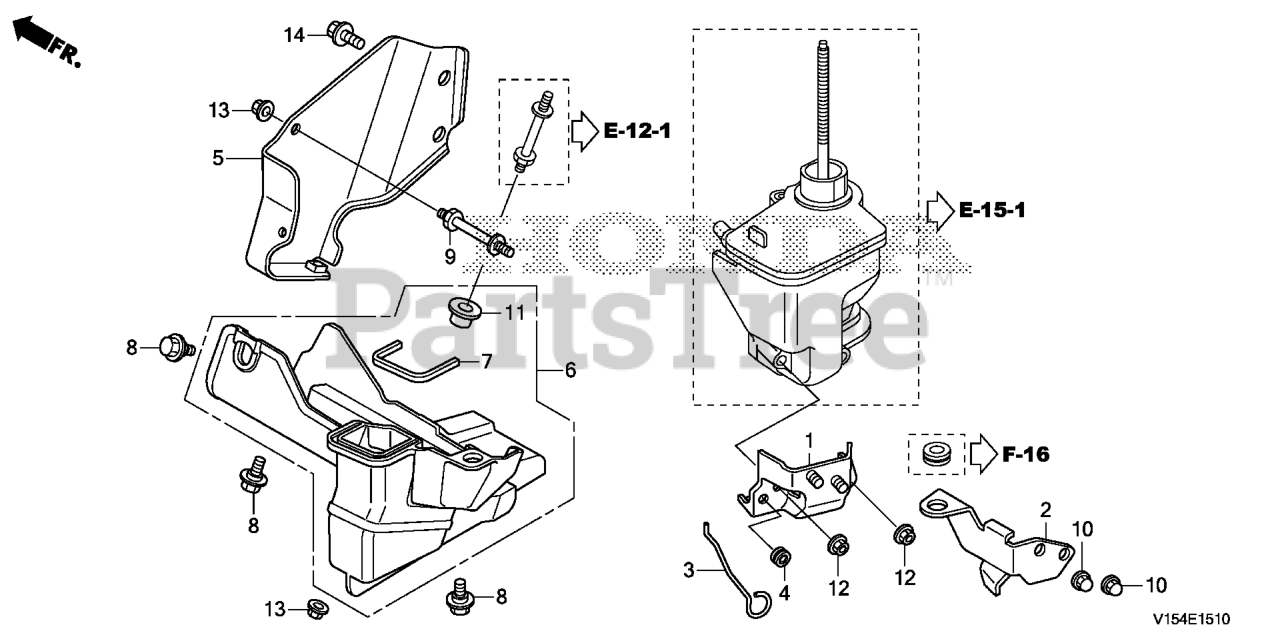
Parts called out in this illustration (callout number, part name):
1	STAY, WIRE HOLDER
2	STAY, L. FR. COVER
3	ROD, CHOKE CONTROL
4	GROMMET, CHOKE ROD
5	SHROUD, FR.
6	GUIDE, AIR
7	SEAL A, AIR GUIDE
8	BOLT, FLANGE (6MM)
9	BOLT, FR. SHROUD
11	COLLAR (6.5X6)
12	NUT, FLANGE (6MM)
13	NUT, FLANGE (6MM)
14	BOLT, FLANGE (8X16) Use from Engine SN 1000016.
